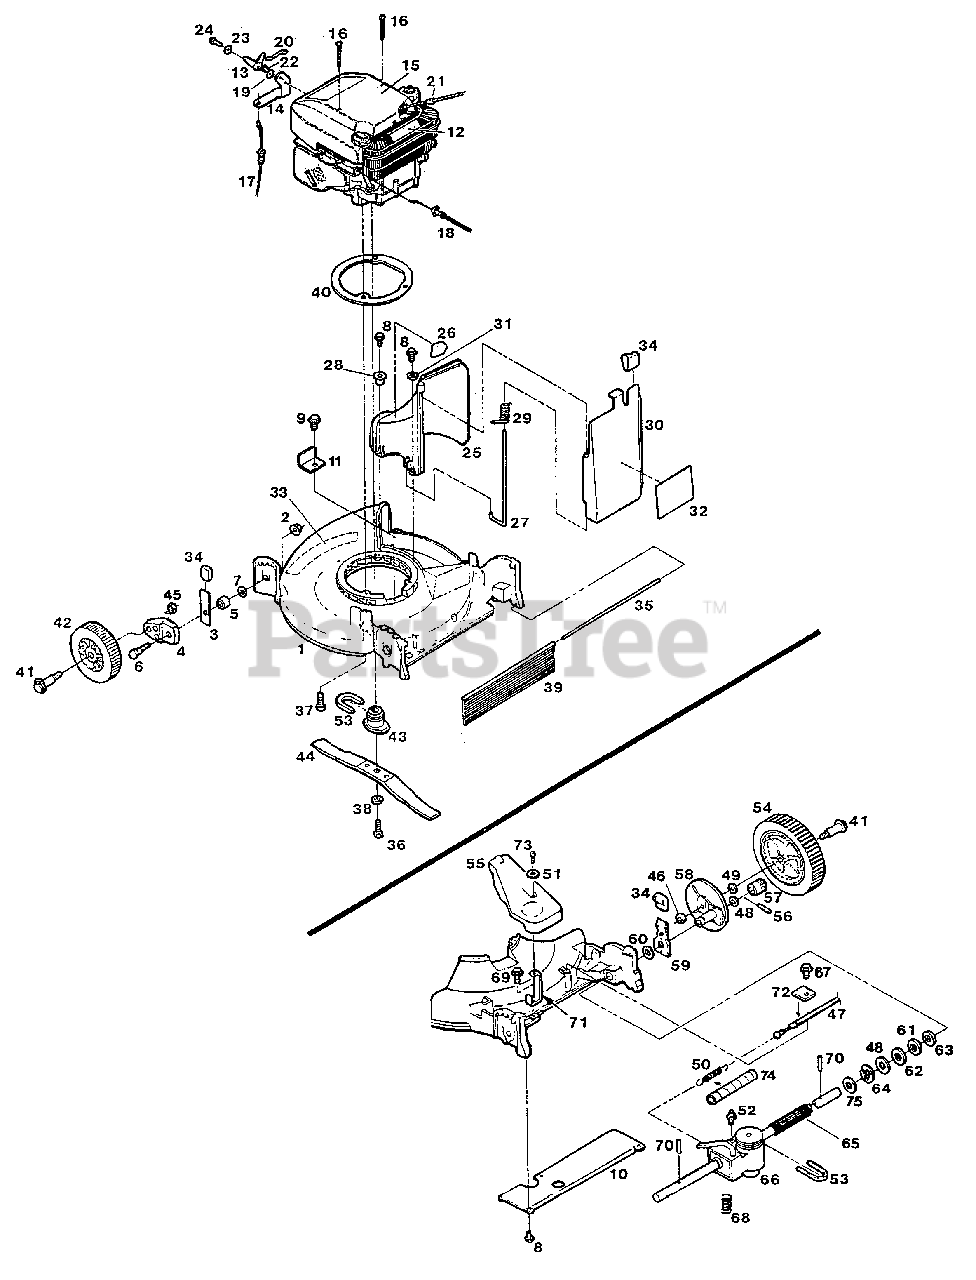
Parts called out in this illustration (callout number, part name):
1	DECK - 21" Red PP
2	NUT - 5/16" Flg. Lock
3	SETTING LEVER ASSY
4	WHEEL ARM - Black
5	SPACER - WHEEL
6	BOLT - Height Adjuster
7	WASHER - 5/16" Flat
8	SCREW - 1/4-20 x 3/4" Hex Tap
9	SCREW - 1/4-20 x 1/2" Hex Tap
10	COVER - Rear Black
11	COVER - Belt Opening Black
12	DECAL - Blade Warning BI/FR
13	BELLCRANK
14	BRACKET - Throttle
15	COVER ENGINE
16	SCREW - #8-32 x 1 1/4" Phil Tap
17	CONTROL - Throttle w/Cable
18	CABLE - Engine/Blade Control
19	SPACER - Stepped
20	THROTTLE LINK
21	ROPE STOP
22	SCREW - #10-24 x 3/8" Hex Tap
23	WASHER - 3/16" flat
24	SCREW - #10-24 x 3/4" Hex Tap
25	DISCHARGE CHUTE
26	DECAL - CPSC DANGER
27	HINGE PIN
29	SPRING - Door Chute
30	DOOR - Chute
31	WASHER - 1/4" Flat
32	DECAL - Door Warning
33	DECAL - Logo 21"
34	PLASTIC TIP - Height Adjuster
35	ROD - Trailing Shield
36	BOLT - 3/8-24 x 1-1/4" HHCS GR8
37	BOLT - 3/8-16 x 2-1/4" Sems
38	WASHER - 3/8 Lock H.D.
39	TRAILING SHIELD - Plastic
40	ENGINE RING BLACK
41	WHEEL BOLT
42	WHEEL - 8"
43	BLADE ADAPTER - 7/8" DIA. PP
44	BLADE - 21"
45	NUT - 3/8-16 Hex
46	NUT 3/8-16 Flg Lock
47	CABLE - Drive Control
48	WASHER - 5/8" x 22 GA. Hard
49	WASHER - 3/8" Flat
50	SPRING - Extension
51	WASHER - 1/4" Flat
52	VENT - Transmission
54	WHEEL - 8" Power Propelled
55	COVER - Drive
56	DRIVE PIN
57	PINION R.H.
58	DRIVE WHEEL SUPPORT Assy- Black
59	SETTING LEVER - Black
60	SPACER - Wheel Rear
61	WASHER - 5/8" x 22 GA. Hard
62	WASHER - 5/8" x 14 GA. Flat
63	WASHER - 5/8" Wave
64	E-RING - 5/8"
65	COVER - Drive Shaft - 7 1/4"
66	TRANSMISSION - 1 spd
67	SCREW - 1/4-20 x 1/2" Hex Tap
68	SPRING - Compression
69	SCREW - #10-16 Hex Tap
70	ROLL PIN - 1/8 x 7/8
71	BRACKET - Belt Cover Black
72	CLAMP - Drive Control Cable
73	SCREW 1/4-20 x 3/4" Phill Tap
74	COVER - Spring
75	WASHER - Thrust
